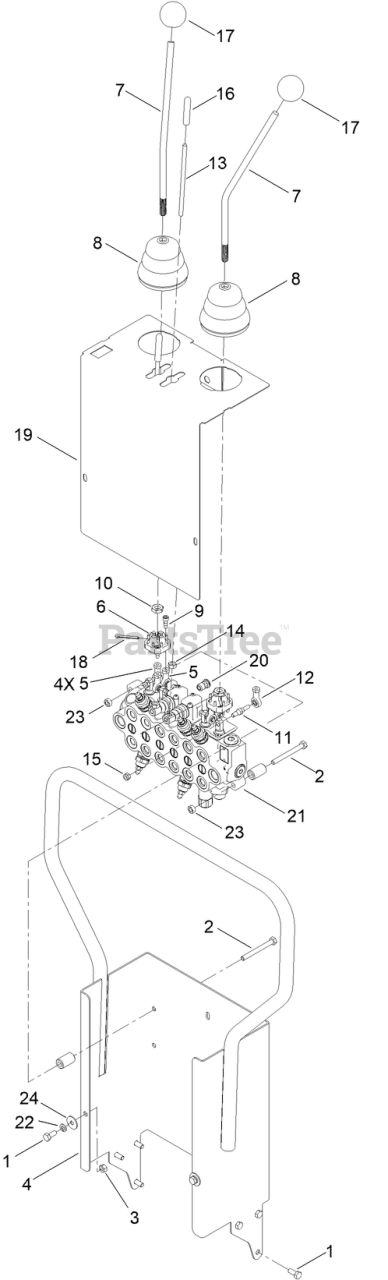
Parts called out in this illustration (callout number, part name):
1	SCREW-HH
2	SCREW-HH
3	5/16-18 LOCKNUT
4	BRACKET-CONTROL ASM
5	JOINT-CONTROL ASM
6	KNUCKLE-CONTROL
7	LEVER-CONTROL
8	BOOT-CONTROL LEVER
9	SCREW-CONTROL
10	NUT-LOCK/CONTROLS
11	ADAPTOR-CONTROL
12	JOINT END-CONTROL
13	CONNECTION ROD-CONTROL
14	NUT-CONTROL
15	NUT-CONTROL
16	COVER-CONTROL
17	KNOB-CONTROL
18	PIN-COTTER
19	PANEL-CONTROL
20	INSERT-PANEL
21	MANIFOLD-HYD
22	WASHER-LOCK
24	WASHER-PLAIN
